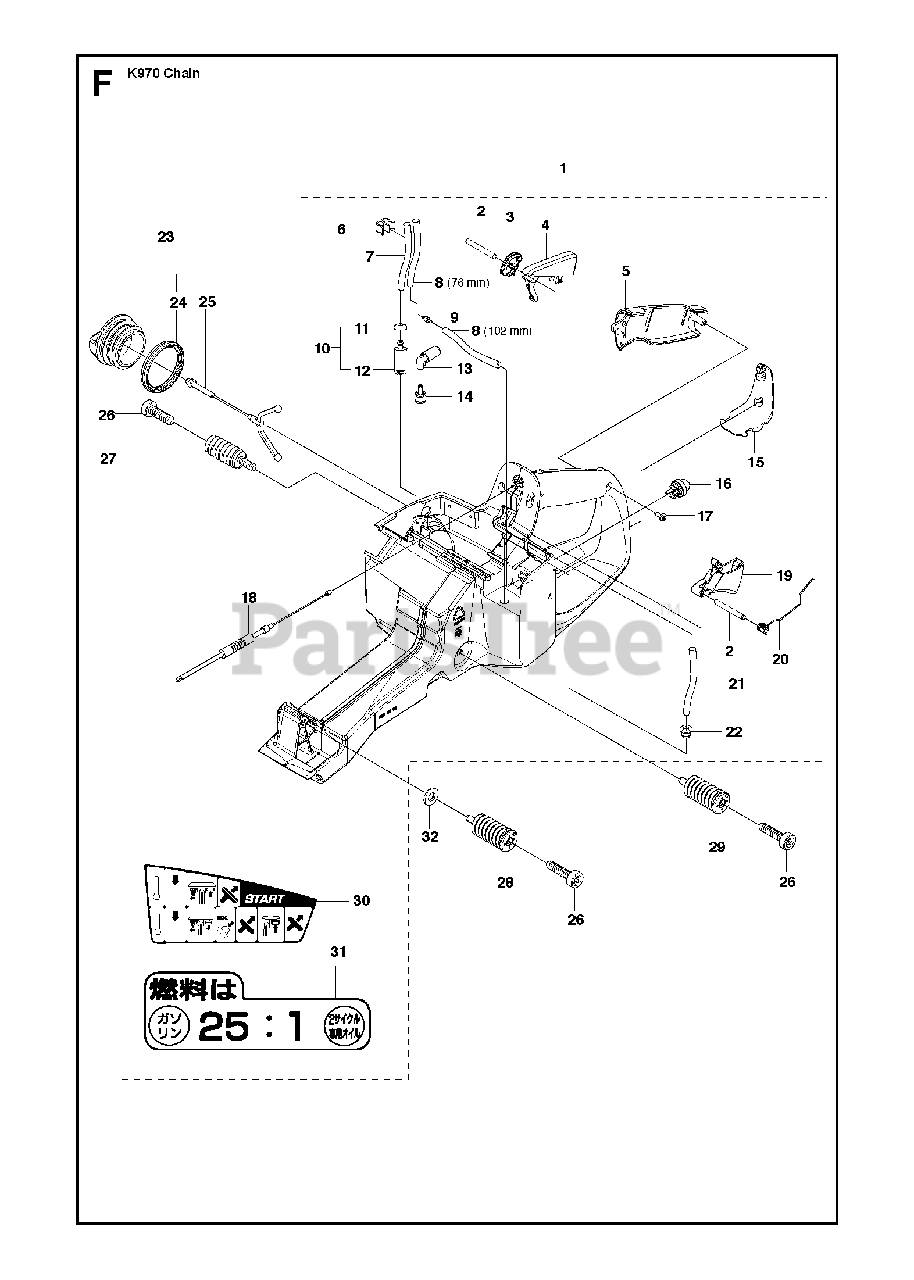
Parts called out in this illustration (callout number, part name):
1	FUEL TANK ASSYIncl. 2 - 21
2	PARALLEL PIN
4	THROTTLE LOCKOUT
7	FUEL HOSE300 mm
8	FUEL HOSE190 mm
10	FUEL FILTERIncl. 11 - 12
13	HOLDER ASSY
14	TANK VENT ASSY
15	GROUND SUPPORT
17	SCREW CCRPANT
18	THROTTLE CABLE ASSY
19	THROTTLE CONTROL
21	FUEL HOSE70 mm
22	BUSHING
23	TANK CAP ASSYIncl. 24 - 25
26	SCREW ITXSCM
27	ANTIVIBRATION ELEMENT
28	ANTIVIBRATION ELEMENT
29	ANTIVIBRATION ELEMENT
